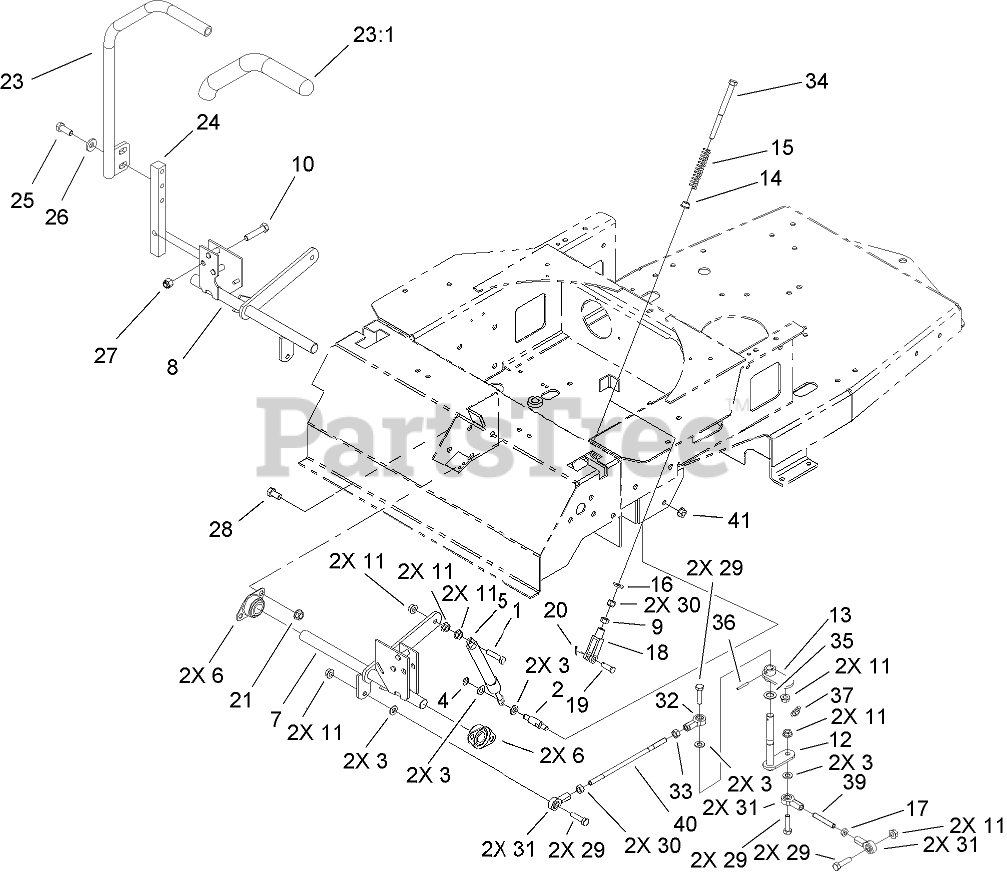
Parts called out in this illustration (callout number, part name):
1	SCREW-HH
2	PIN-DAMPER
3	WASHER-PLAIN
4	RING-RETAINING, EXT
5	Damper-Control, Motion
6	BEARING-FLANGE, SIDE
7	BRACKET-MOTION CONTROL, LH
8	BRACKET-MOTION CONTROL, RH
9	NUT-LOCK
10	SCREW-HH
11	NUT-HF
12	PIVOT ASM
13	PIVOT PLATE ASM
14	BUSHING-FLANGED
15	SPRING-RETURN, NEUTRAL
16	WASHER-FLAT
17	NUT-JAM
18	YOKE-ADJUSTABLE
19	PIN-CLEVIS
20	PIN-COTTER
21	NUT-HHF, WHIZ
23	RH LEVER ASM
23:1	GRIP-CONTROL, MOTION
24	ARM-SHAFT, CONTROL
25	SCREW-HH
26	WASHER-BELLEVILLE
27	NUT-LOCK, NI
28	SCREW-HH
29	SCREW-HH
30	NUT-HEX
31	BALLJOINT-RH
32	BALLJOINT-LH
34	BOLT-RETURN, NEUTRAL
35	WASHER
36	PIN-ROLL
37	FITTING-LUBE, 45 DEG
39	LINKAGE-LOWER, LH
40	LINKAGE-UPPER
41	NUT-HF
